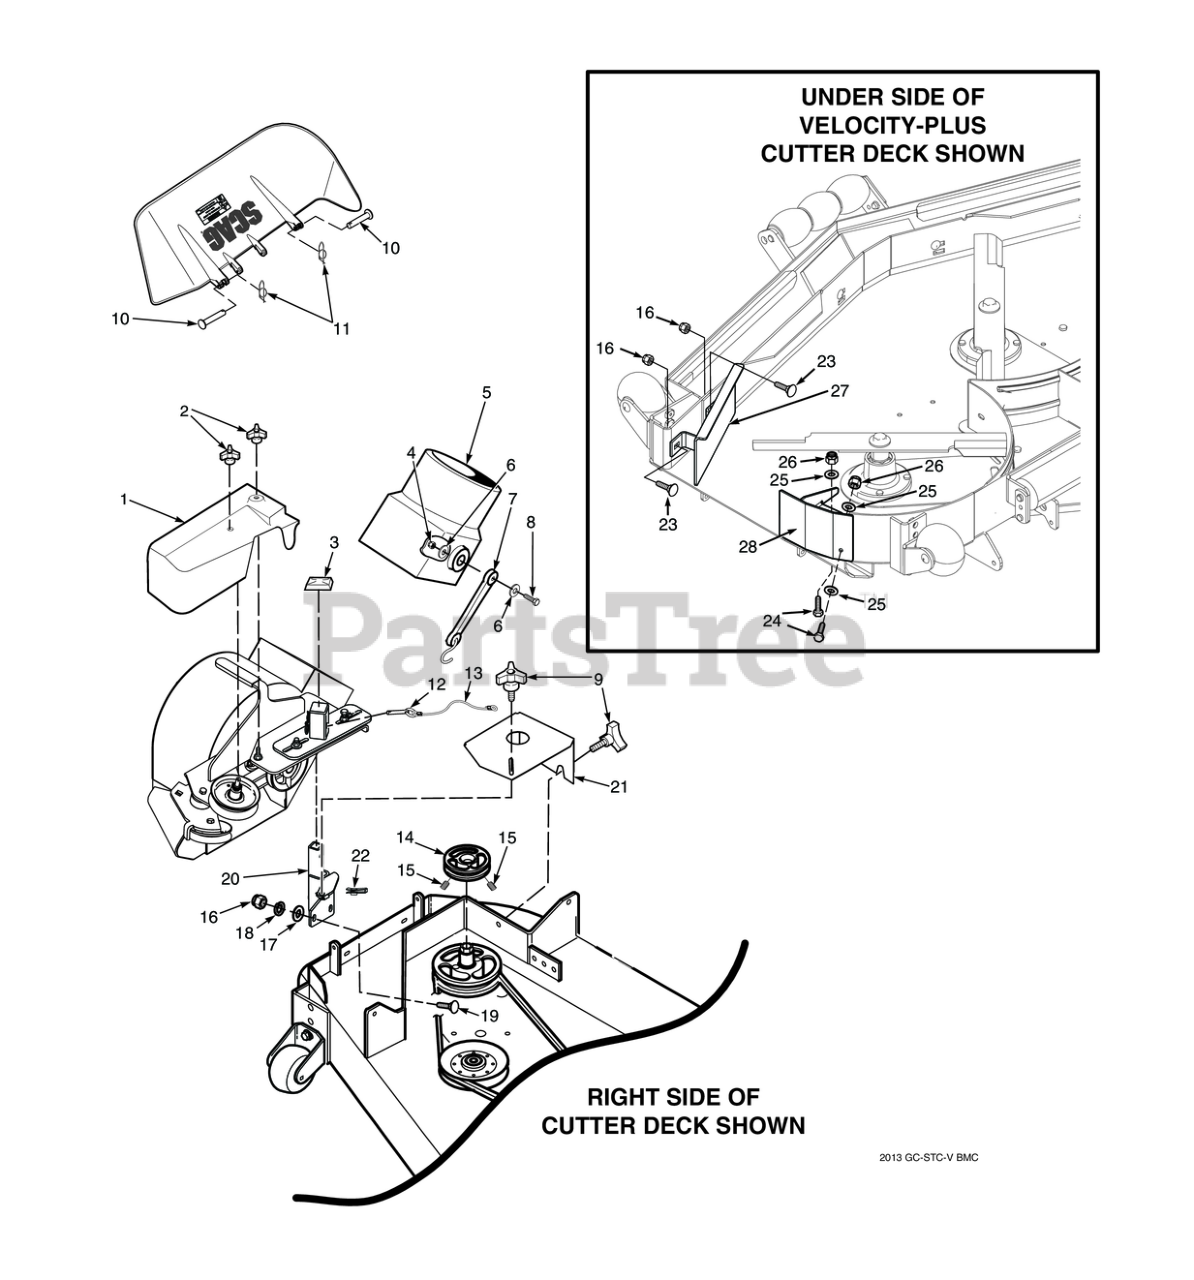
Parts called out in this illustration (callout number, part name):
1	Belt Cover, GC-STT - 61"
1	Belt Cover, (STT-52 & STTII-52)
2	Wing Nut, 3/8-16 (Small) Top side
3	Cap, Square Vinyl
4	HEX, NUT, ELASTIC STOP LOCK, 1/4-20
5	Adapter, Blower GC-STC,
6	Flatwasher, 1/4" (.312 x .750 x .065")
7	Rubber Strap 7-3/4"
8	SERR. FLG. HEX HEAD CAPSCREW, 5/16-18 X 3/4
9	Knob, w/stud 3/8-16 x 1-1/4"
10	Clevis Pin, 5/16 x 1-1/2"
11	Pin, Rue Cotter 5/16 Dia.
12	Pin, Ring 1/2 x 2-1/4"
13	Lanyard, Deck Height Pin
14	Pulley, 5-1/2" Dia. - 1.125" Bore, (61")
15	Setscrew, Hex Socket Knurl Cup Pt. 5/16 - 18 (nylock)
16	HEX NUT, ELASTIC STOP LOCK, 3/8-16
17	Lockwasher, 3/8" Spring, Kawasaki FX / FS
18	Flatwasher, 3/8" Special (.391 x .938 x .105)
19	SHORT SQ. NECK CARRIAGE BOLT, 3/8-16 X 1-1/4"
19	Bolt, Hex Head 1/2-13 x 1-1/2", (STT-52 & STTII-52)
20	Mounting Post Weldment, Blower, (61")
21	Belt Cover Assembly, GC-STT-61V w/Cap
22	U-Nut, 3/8-16 (short)
23	Carriage Bolt, 3/8-16 x 1.0"
24	Bolt, Heax Head 5/16-18 x 1" (48V / 52V)
25	Flatwasher, 5/16-.375 x .875 x .083 (35BV & 37BV-EFI)
26	HEX NUT, ELASTIC STOP LOCK, 5/16-18
27	Baffle Weldment - 61" Deck
28	Baffle, Turbo - 61" Deck
